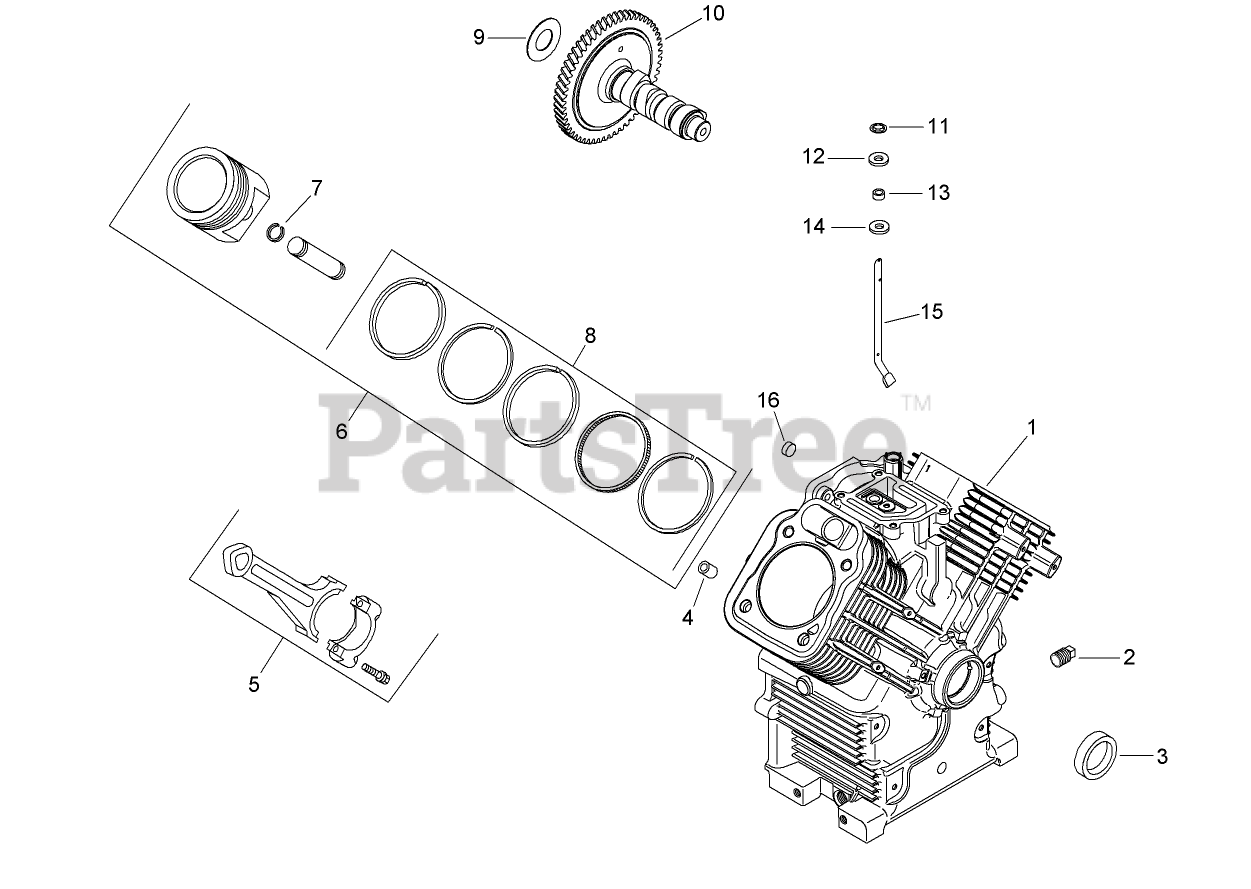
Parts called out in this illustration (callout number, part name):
1	CRANKCASE-MINI BLOCK
2	PLUG-PIPE HEAD, 3/8
3	SEAL-OIL (HELIX LIP)
4	PIN-LOCATING
5	ROD-CONNECTING (STD)
5	ROD-CONNECTING (.25)
6	PISTON AND RING KIT (STD)
6	PISTON W/RING SET (.08)
6	Piston and Ring Set (.25)
6	PISTON W/RING SET KIT (.50)
7	RETAINER-PIN, PISTON
8	PISTON RING SET (STD)
8	RING SET (.08)
8	PISTON RING SET (.25)
8	RING SET (.50)
9	SHIM-CAMSHAFT (WHITE .028)
9	SHIM-CAMSHAFT (BLUE .03)
9	SHIM-CAMSHAFT (RED .032)
9	SHIM-CAMSHAFT (YELLOW .034)
9	SHIM-CAMSHAFT (GREEN .036)
9	SHIM-CAMSHAFT (GRAY .038)
9	SHIM-CAMSHAFT (BLACK .04)
10	CAMSHAFT KIT (INCLUDES 12 422 08-S & 25 357 14-S)
11	RETAINER-RING
12	WASHER-FLAT (9MM)
13	SEAL-CROSS SHAFT, GOVERNOR
14	WASHER-FLAT (11/32)
15	SHAFT-CROSS, GOVERNOR
16	PLUG-CUP
